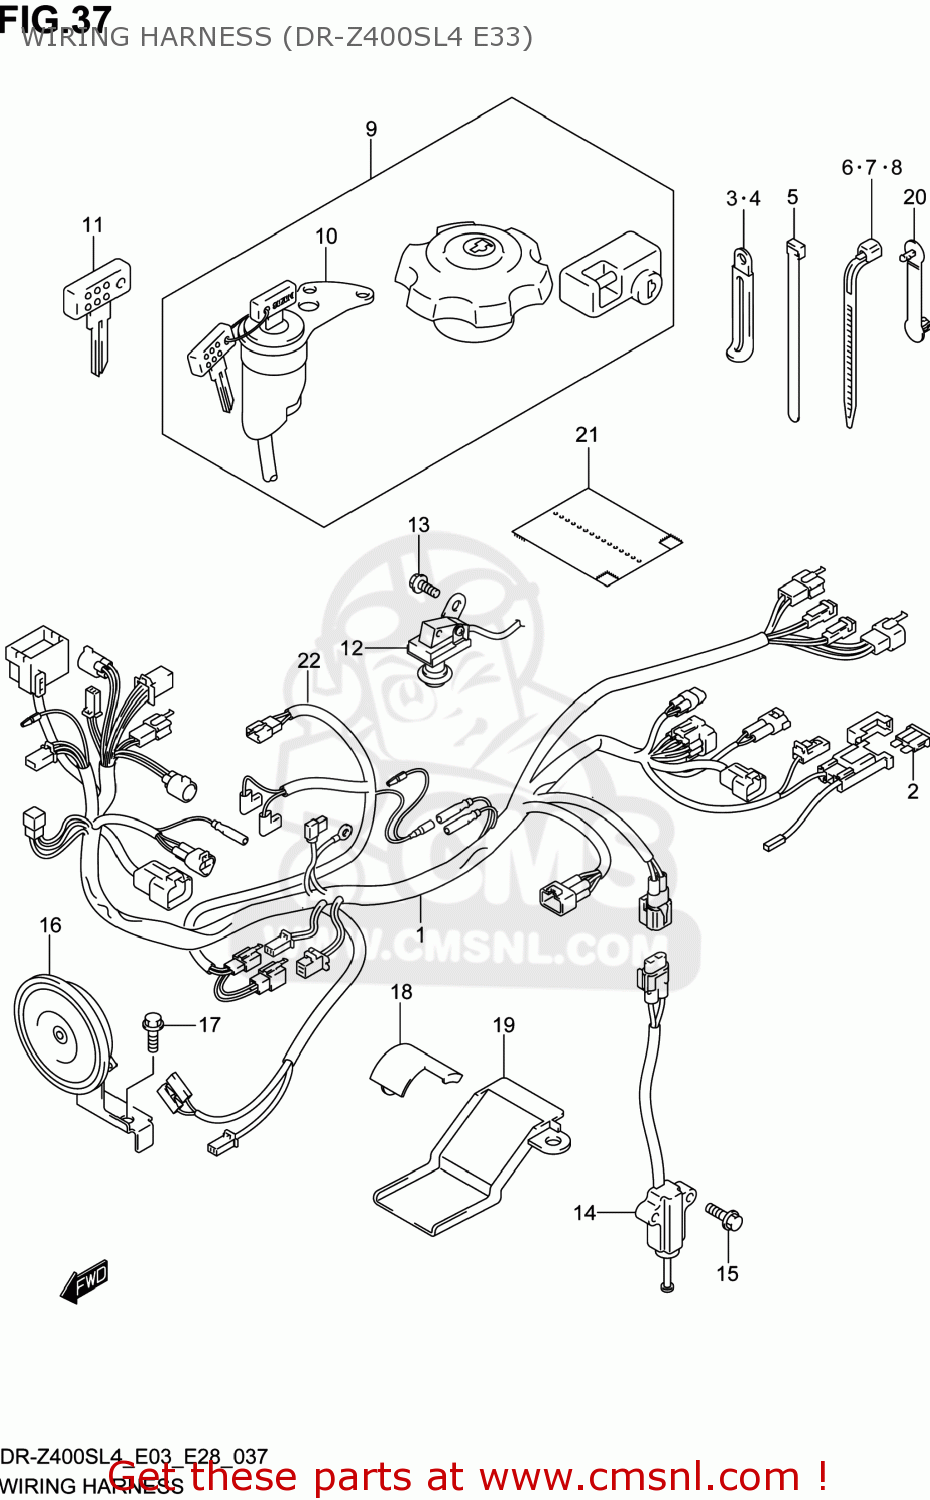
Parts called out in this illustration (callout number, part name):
1	HARNESS,WIRING
2	FUSE(20A)
3	CLAMP(L:45)
4	CLAMP(L:80)
5	CLAMP(L:145)
6	CLAMP(L:125)
7	CLAMP(L:165)
8	CLAMP(L:235)
9	LOCK SET
10	SWITCH ASSY,IGNITION
11	KEY,BLANK(TYPE:C)
12	SWITCH ASSY
13	SCREW
14	SWITCH ASSY,SIDE STAND
15	BOLT
16	HORN ASSY
17	BOLT
18	PROTECTOR,WIRING HARNESS
19	PROTECTOR,WIRING HARNESS
20	CLAMP(L:63)
21	COVER,WIRING HARNESS
22	WIRE,CARB HEATER
